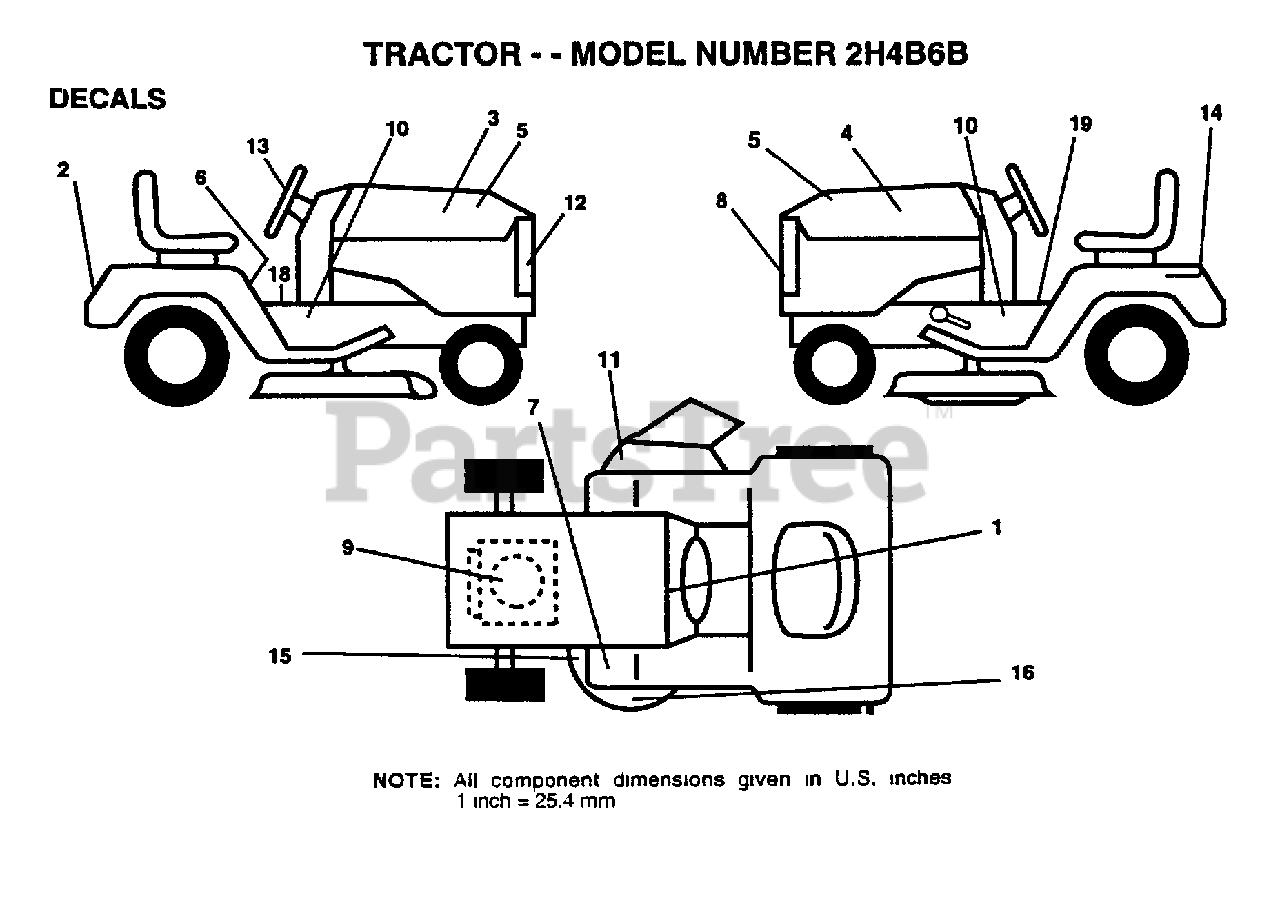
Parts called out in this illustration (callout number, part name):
1	DECAL.DASH.INSTR.
2	FENDER DECAL
3	DECAL HOOD RH RLY
4	DECAL HOOD LH RLY
6	DECAL CAUTION
7	DECAL T
9	DECAL.ENG.272632
10	DECAL CHAS 42 HYD
11	"DECAL, WARNING"
12	GRILL DECAL
13	"DECAL,STR WHL"
14	DECAL
15	DECAL
18	DECAL SADL HYDRO
19	DECAL BRAK PARK
